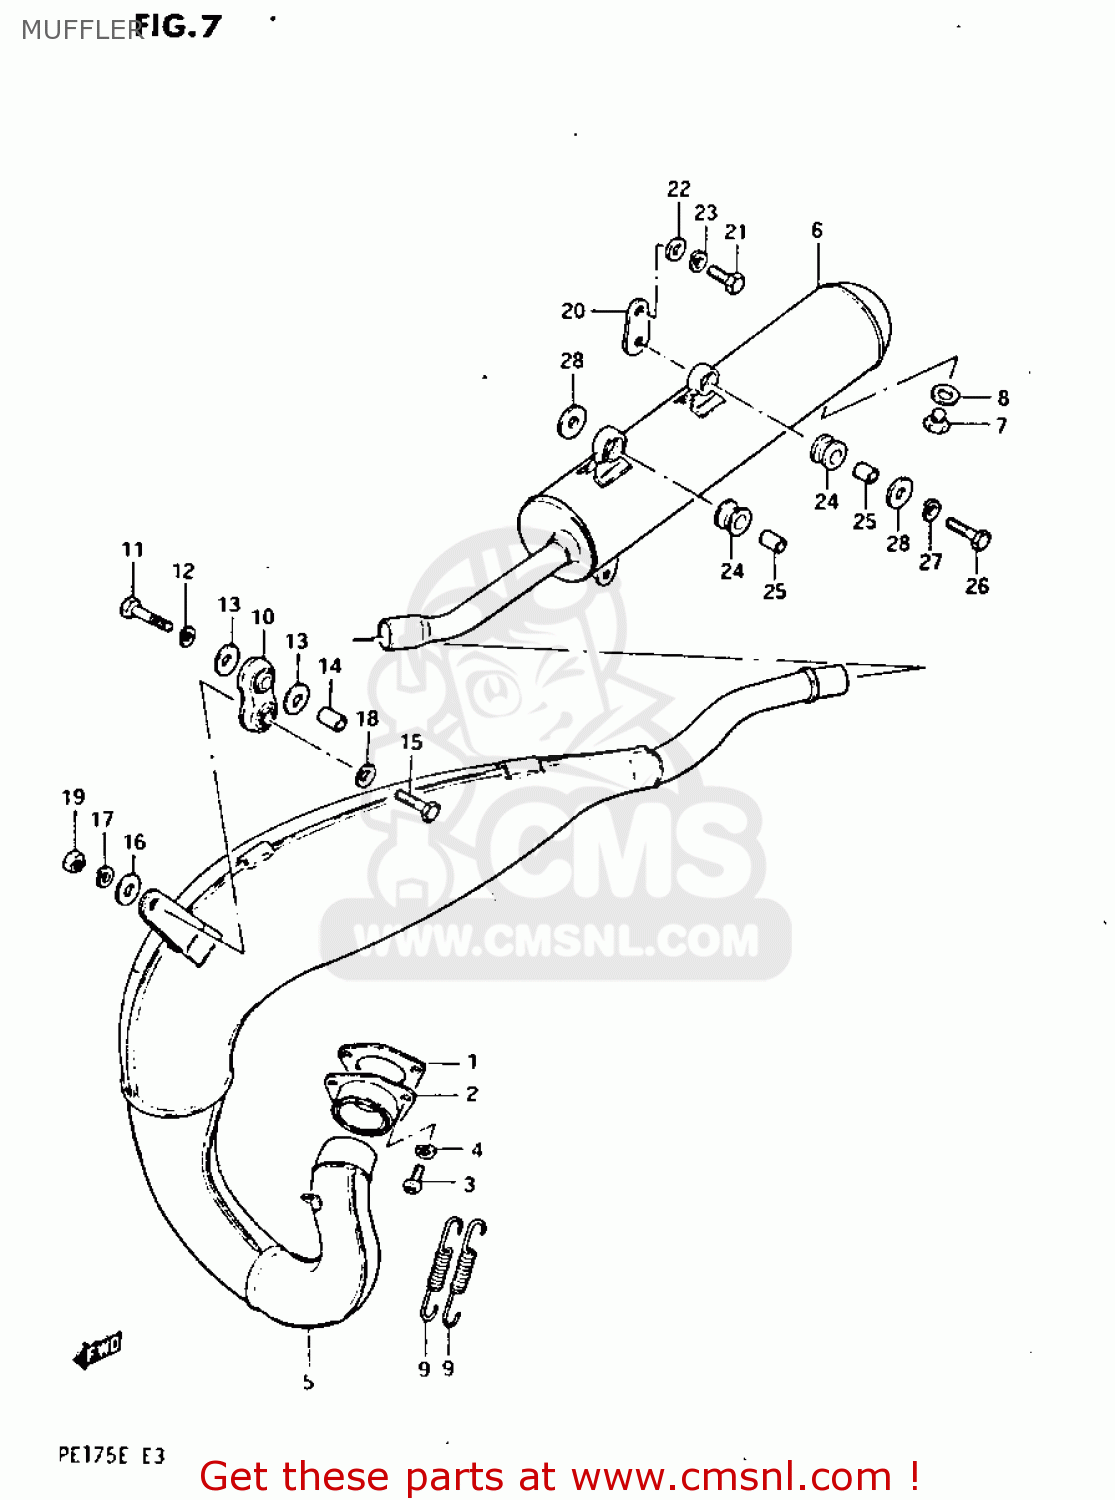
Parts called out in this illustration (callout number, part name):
1	GASKET,EXHAUST PIPE (MCA)
2	FLANGE,EXHAUST PIPE
3	SCREW
4	WASHER,LOCK
5	BODY,MUFFLER
6	MUFFLER ASSEMBLY,SECOND
7	PLUG(12X9)
8	GASKET(12.1X16.2X3.7) (NAS)
9	SPRING
10	DAMPER,MUFFLER
11	BOLT 8X50
12	LOCK WASHER
13	WASHER
14	SPACER (8.2X12X17)
15	BOLT
16	WASHER
17	LOCK WASHER
18	WASHER
19	NUT
20	BRACKET,SECOND MUFFLER
21	BOLT
22	WASHER
23	LOCK WASHER
24	CUSHION
25	SPACER (8.2X12X17)
26	BOLT
27	LOCK WASHER
28	WASHER (8.5X29X1.6)
